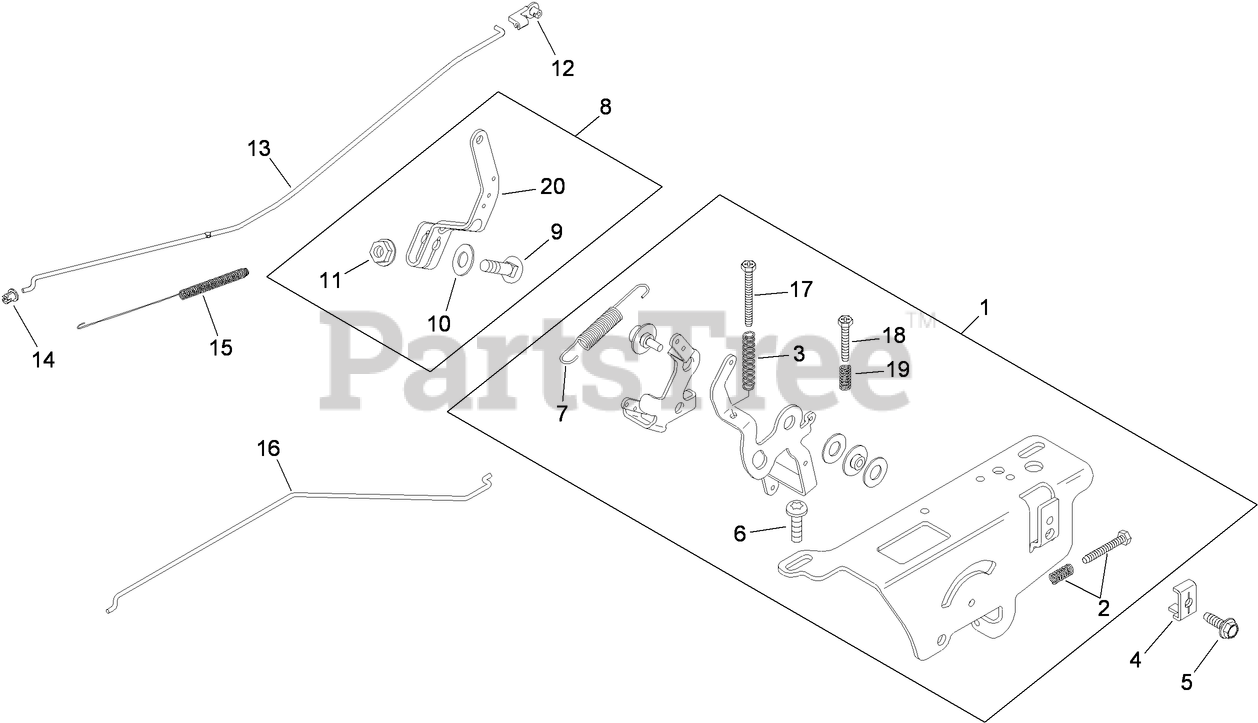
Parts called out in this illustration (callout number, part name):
1	SPEED CONTROL ASM (INCLUDES REF 2, 3, 6 [QTY 1], 7, 17, 18, 19)
2	IDLE ADJUSTING SCREW AND SPRING KIT
3	SPRING-CONTROL, SPEED (LONG)
4	CLAMP-CABLE
5	SCREW-FLANGE, THREAD FORMING (M5X0.8X16)
6	Screw-Socket, 6 Lobed (Thread Forming, M6x1.0x20)
7	Spring-Governor
8	GOVERNOR LEVER ASM (INCLUDES REF 12-15)
9	Bolt-Square Neck, Round Head (1/4-20x1)
10	Washer-Lock, Internal Tooth (1/4)
11	Nut-Flange, Hex (1/4-20)
12	BUSHING-RETAINING, LINKAGE
13	LINKAGE-THROTTLE
14	BUSHING-LINKAGE, THROTTLE
15	Spring-Linkage
16	Linkage-Choke (Single Wire)
17	SCREW-PHL THD FRM (M4X0.7X38)
18	Screw-Thread Forming (M4x0.7x25)
19	Spring-Control, Speed
20	Lever-Governor
